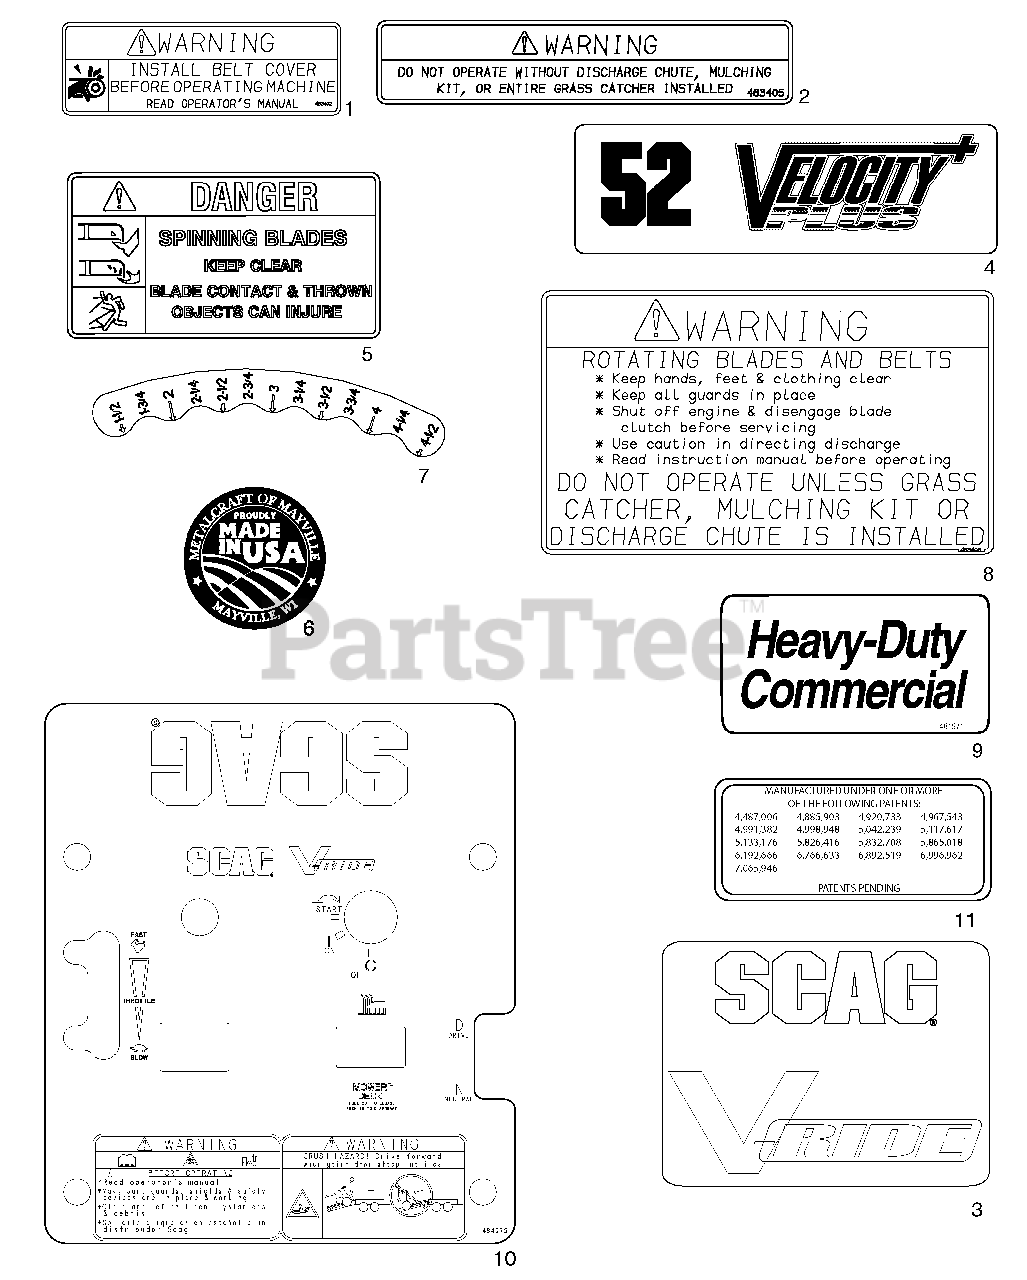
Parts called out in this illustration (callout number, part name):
1	Decal, Warning - Belt Cover
2	Decal, Warning
3	Decal, Belt Cover
4	Decal, 36A
5	Decal, Spinning Blades
6	Decal, Metalcraft - Made in USA
7	Decal, Height-of-Cut
8	Decal, Warning - Knives
9	Decal, Heavy Duty Commercial
10	Decal, Instrument Panel
11	Decal, Patents
